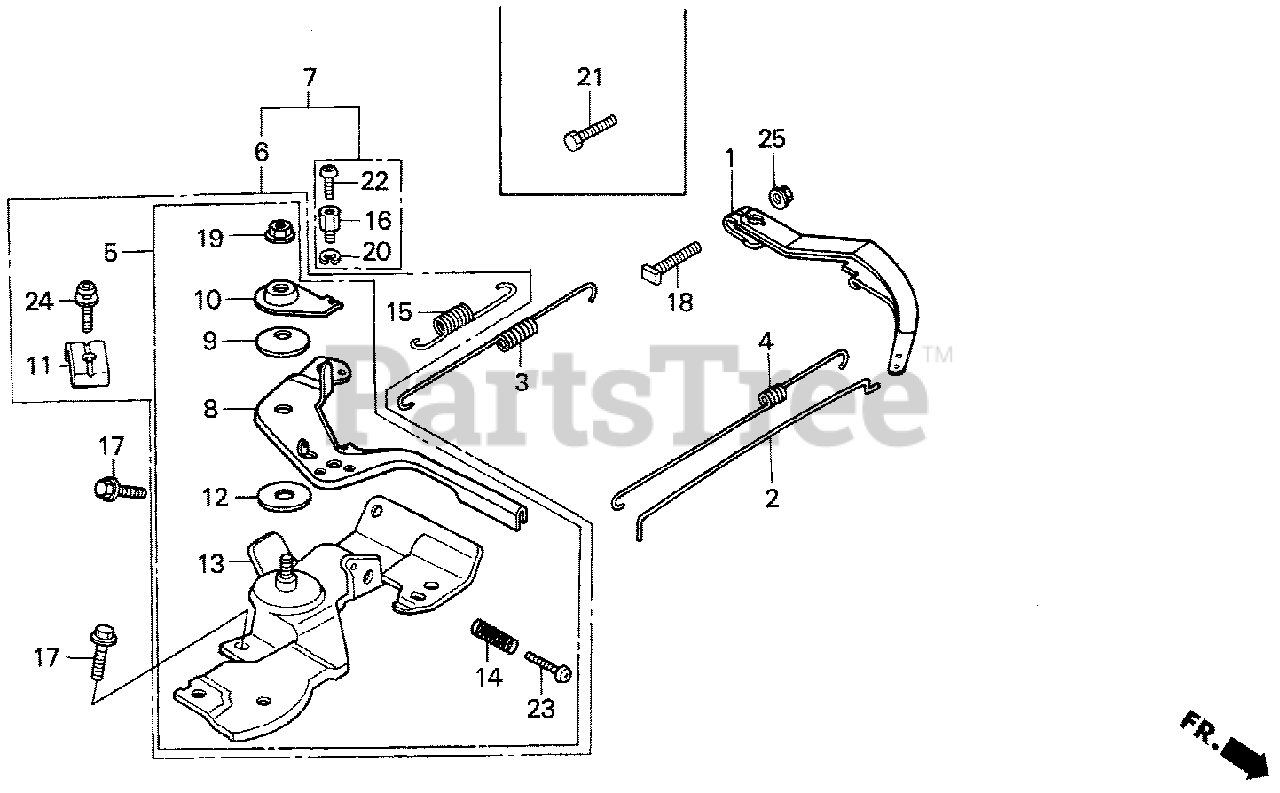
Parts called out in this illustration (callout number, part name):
1	ARM, GOVERNOR
2	ROD, GOVERNOR
3	SPRING, GOVERNOR
4	SPRING, THROTTLE RETURN
6	CONTROL ASSY. (REMOTE)
8	LEVER, CONTROL
9	SPRING, LEVER
10	WASHER, CONTROL LEVER
11	HOLDER, CABLE
12	SPACER, CONTROL LEVER
13	BASE, CONTROL (REMOTE)
14	SPRING, CONTROL ADJUSTING
15	SPRING, CABLE RETURN
17	BOLT, FLANGE (6X12) (CT200)
18	BOLT, GOVERNOR ARM
19	NUT, SELF-LOCK (6MM)
19	NUT, FLANGE (6MM)
21	BOLT, HEX. (6X20)
23	SCREW, PAN (5X20)
24	SCREW-WASHER (5X16)
25	NUT, FLANGE (6MM)
